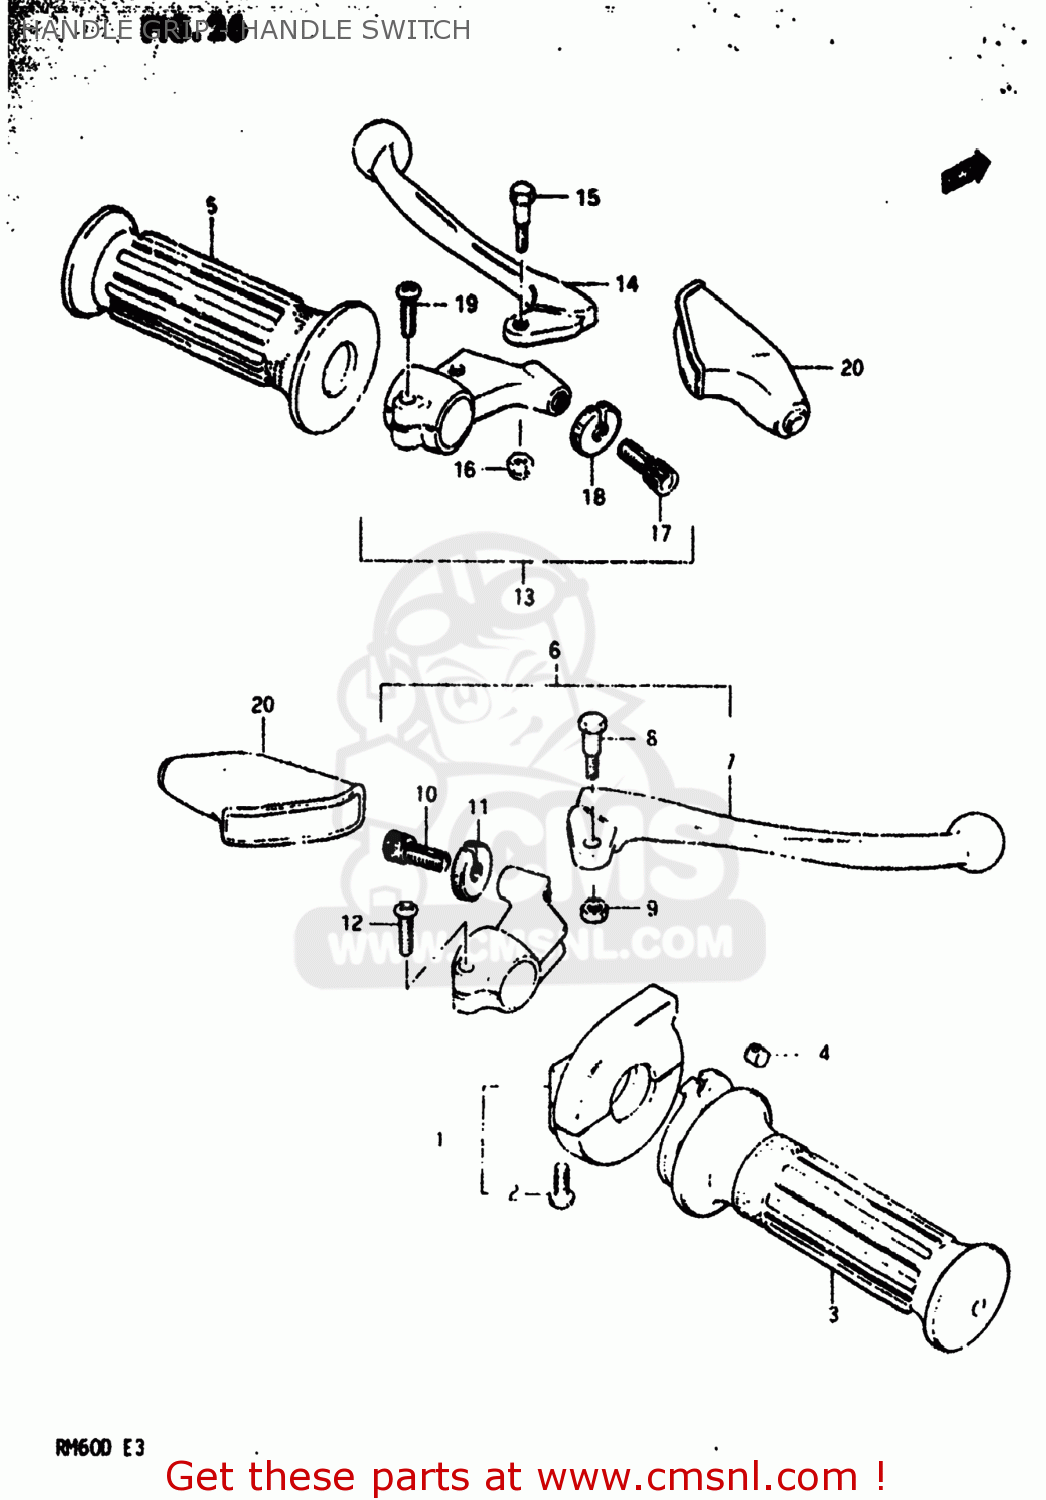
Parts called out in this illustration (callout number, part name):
1	CASE ASSY,THROTTLE
2	SCREW
3	GRIP,THROTTLE
4	PIECE,THROTTLE END
5	GRIP,L
6	LEVER ASSEMBLY,BRAKE
7	LEVER,BRAKE
8	BOLT,LEVER
9	NUT 6MM
10	ADJUSTER,CABLE
11	NUT,CABLE ADJUSTER
12	SCREW
13	LEVER ASSY,CLUTCH
14	LEVER,CLUTCH
15	BOLT,LEVER
16	NUT 6MM
17	ADJUSTER,CABLE
18	NUT,CABLE ADJUSTER
19	SCREW
20	COVER,CLUTCH LEVER
